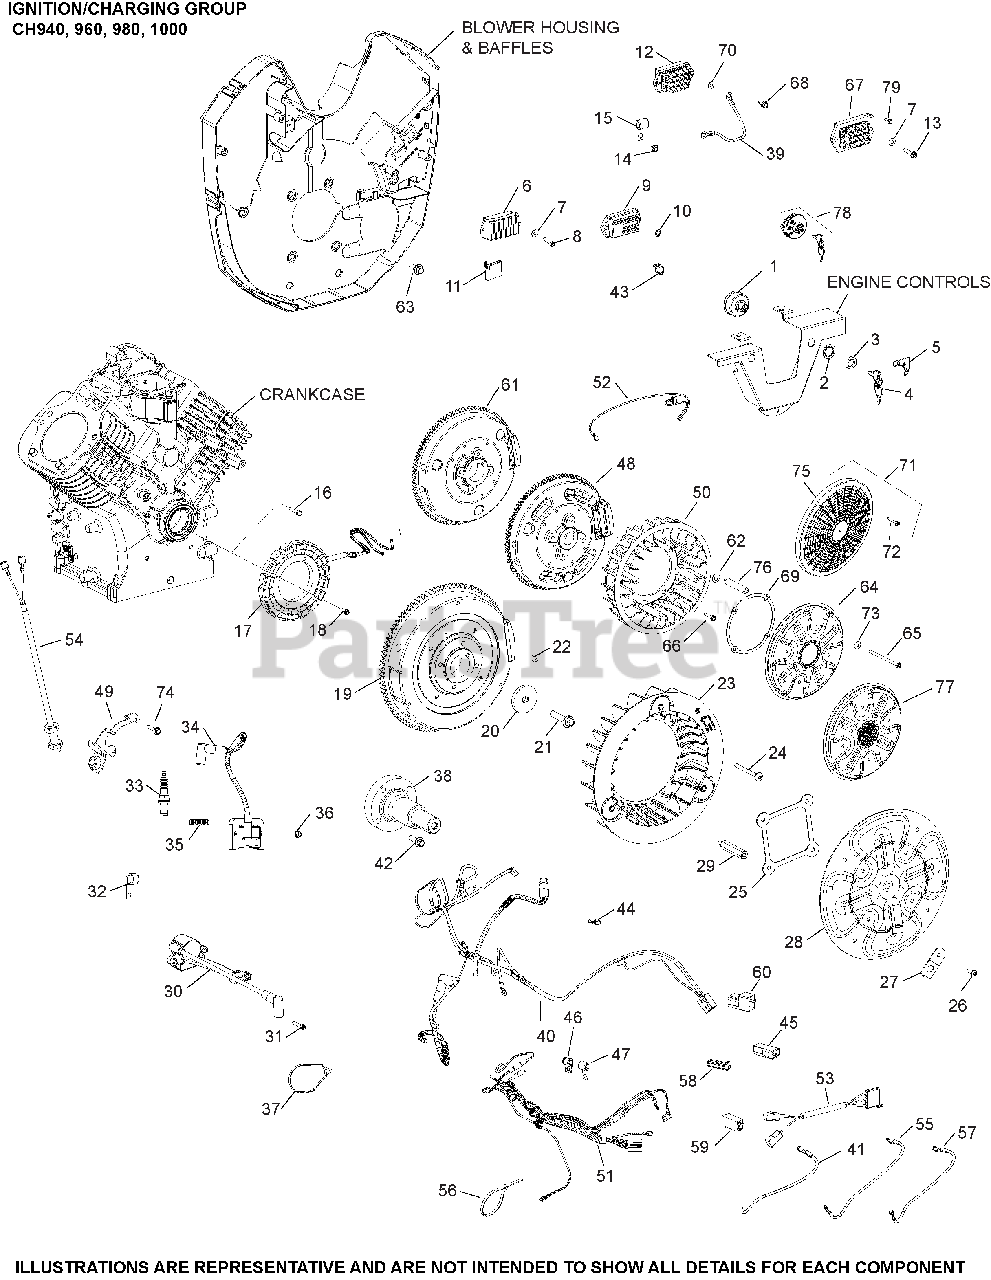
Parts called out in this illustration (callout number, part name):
1	SWITCH ASSEMBLY, KEY
2	WASHER, INTERNAL TOOTH
3	NUT, KEY SWITCH
4	KEY, SET OF 2
5	DECAL, KEYSWITCH
9	REGULATOR, RECTIFIER (20-30AMP,FW W/O USE 25 403 39-S
10	WASHER, INT TOOTH LOCK 1/4"
11	CONNECTOR
13	SCREW, HEX FLANGE HI-LO
15	CLIP, CABLE
17	KIT, 25 AMP STATOR ASSY.
18	SCREW, THREAD FORMING
19	FLYWHEEL ASSEMBLY
20	WASHER, FLAT 13/32"
21	SCREW, FLG M10X1.5X45 - (#25086361S)
22	KEY, 3/16" X 5/8"
23	FAN
30	MODULE, IGNITION
32	CLIP, CABLE
33	PLUG, SPARK
37	TIE, CABLE
40	HARNESS, WIRING (KEY SWITCH)
41	LEAD, B+ TO STARTER SOLENOID
49	BRACKET, SENSOR MOUNTING
54	KIT, SPEED SENSOR
62	WASHER, SPRING 10 MM
65	SCREW, HEX HEAD
66	SCREW, THREAD THROWING
68	SCREW, THREAD FORMING
69	RING, SUPPORT
73	WASHER, FLAT 1/4" (O.D. 5/8")
76	SPACER, GRASS SCREEN
77	SCREEN, GRASS
79	SCREW, THREAD FORMING
